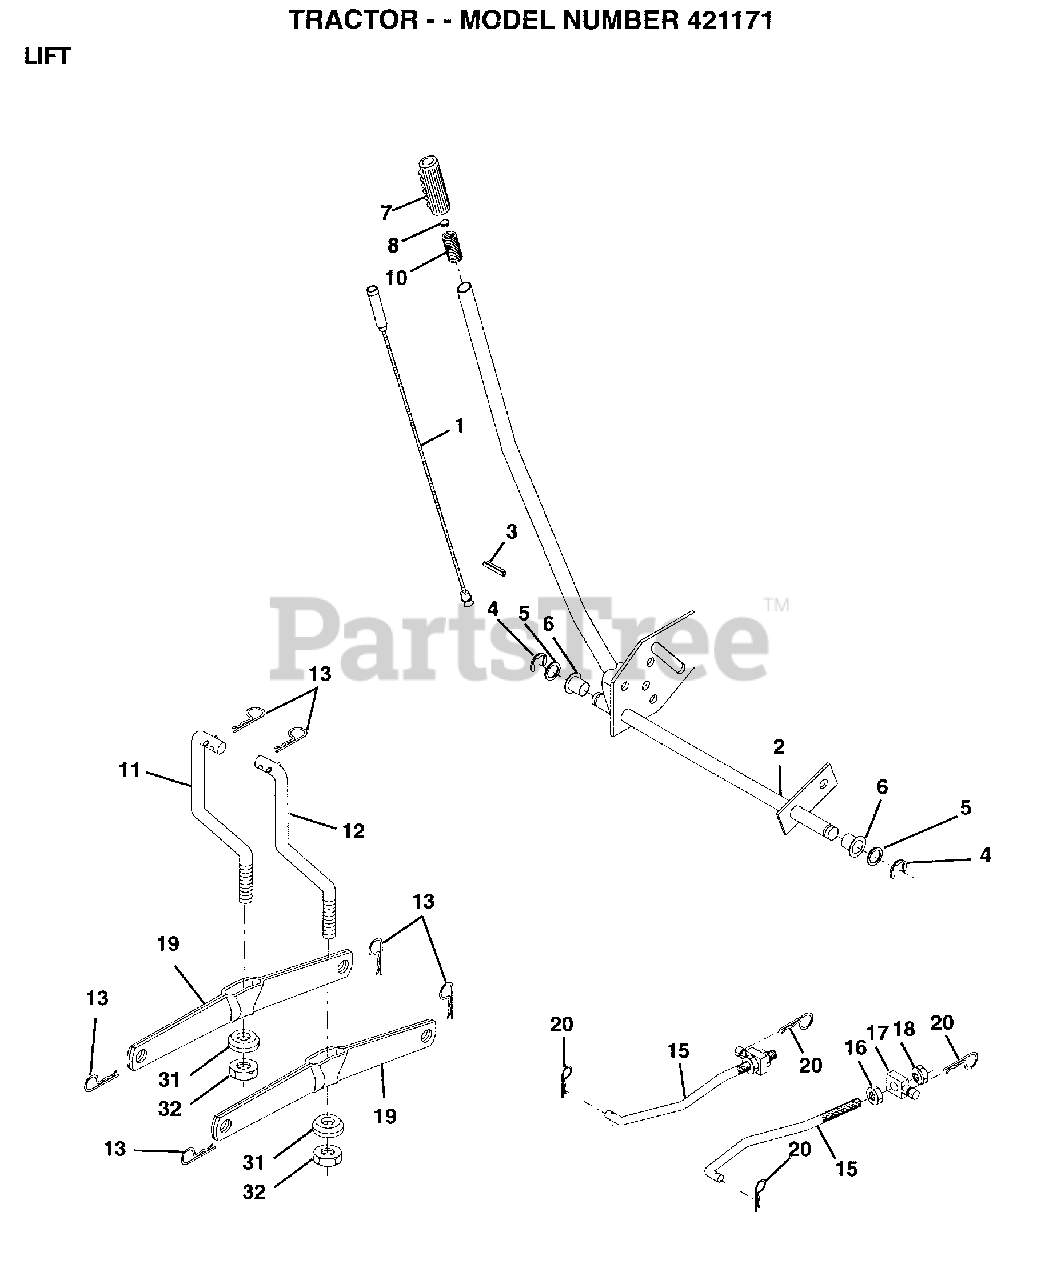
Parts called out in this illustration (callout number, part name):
1	WIRE ASM INNER W/PLUNGER
2	HANDLE.LIFT.LH.
3	PIN GROOVE
5	WASHER
6	NYLON BEARING
7	GRIP
15	LINK.FRONT
16	NUT
17	TRUNION
18	NUT.LK.W/WSH.1/2.
19	ARM SUSP REAR
20	RETAINER.SPRING
31	BEARING PVT LH
32	NUT.CROWNLOCK.3/8
